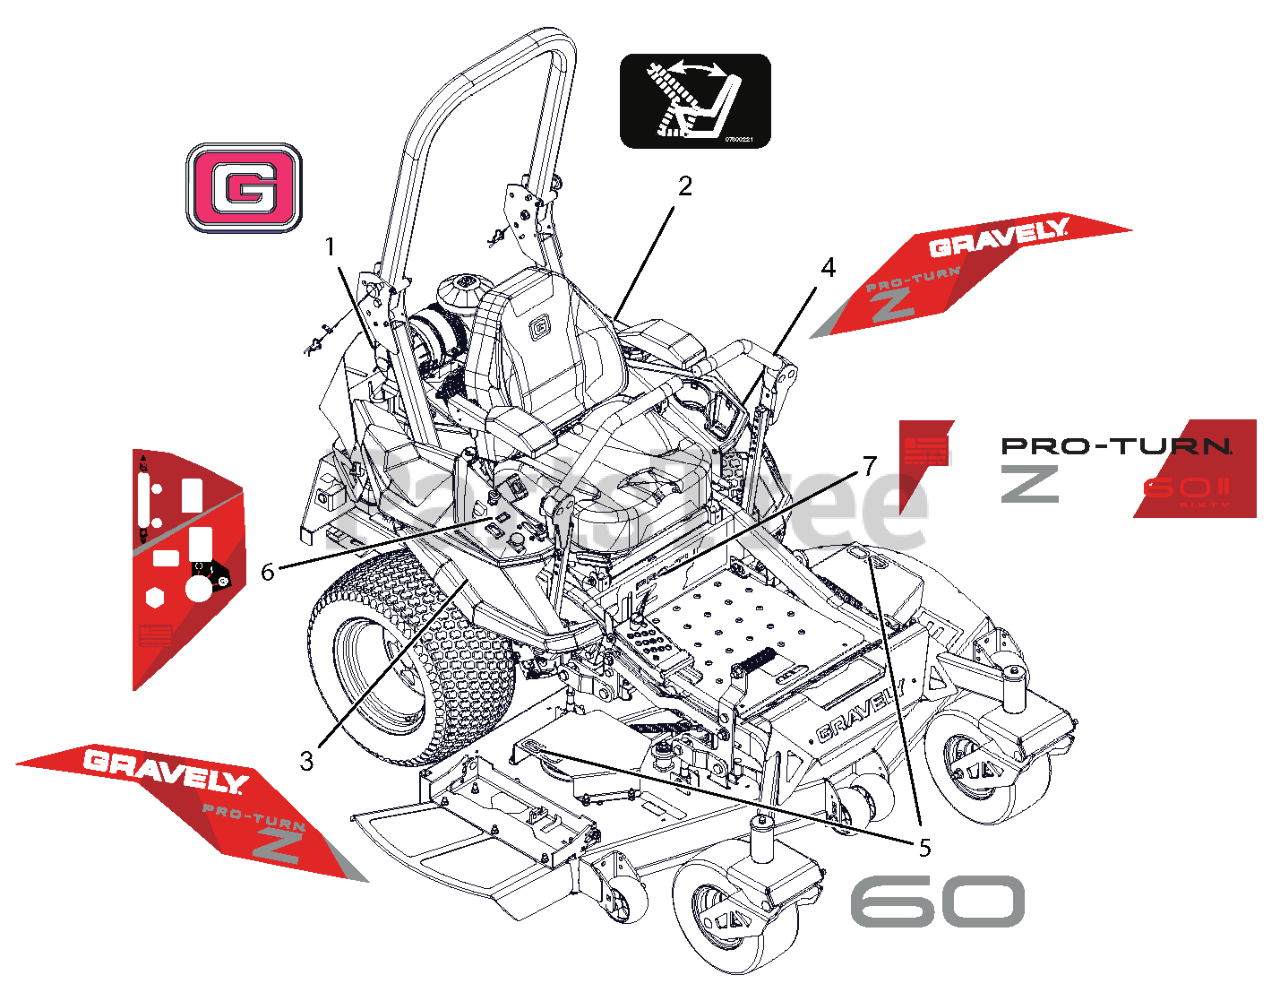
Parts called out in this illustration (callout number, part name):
1	DECAL, GRAVELY BRAND
2	DECAL - SEAT RELEASE
3	DECAL, FENDER RH - PTZ
4	DECAL, FENDER LH - PTZ
5	DECAL, DECK - 60
6	DECAL, CONTROL PANEL
7	DECAL, PTZ - 60
